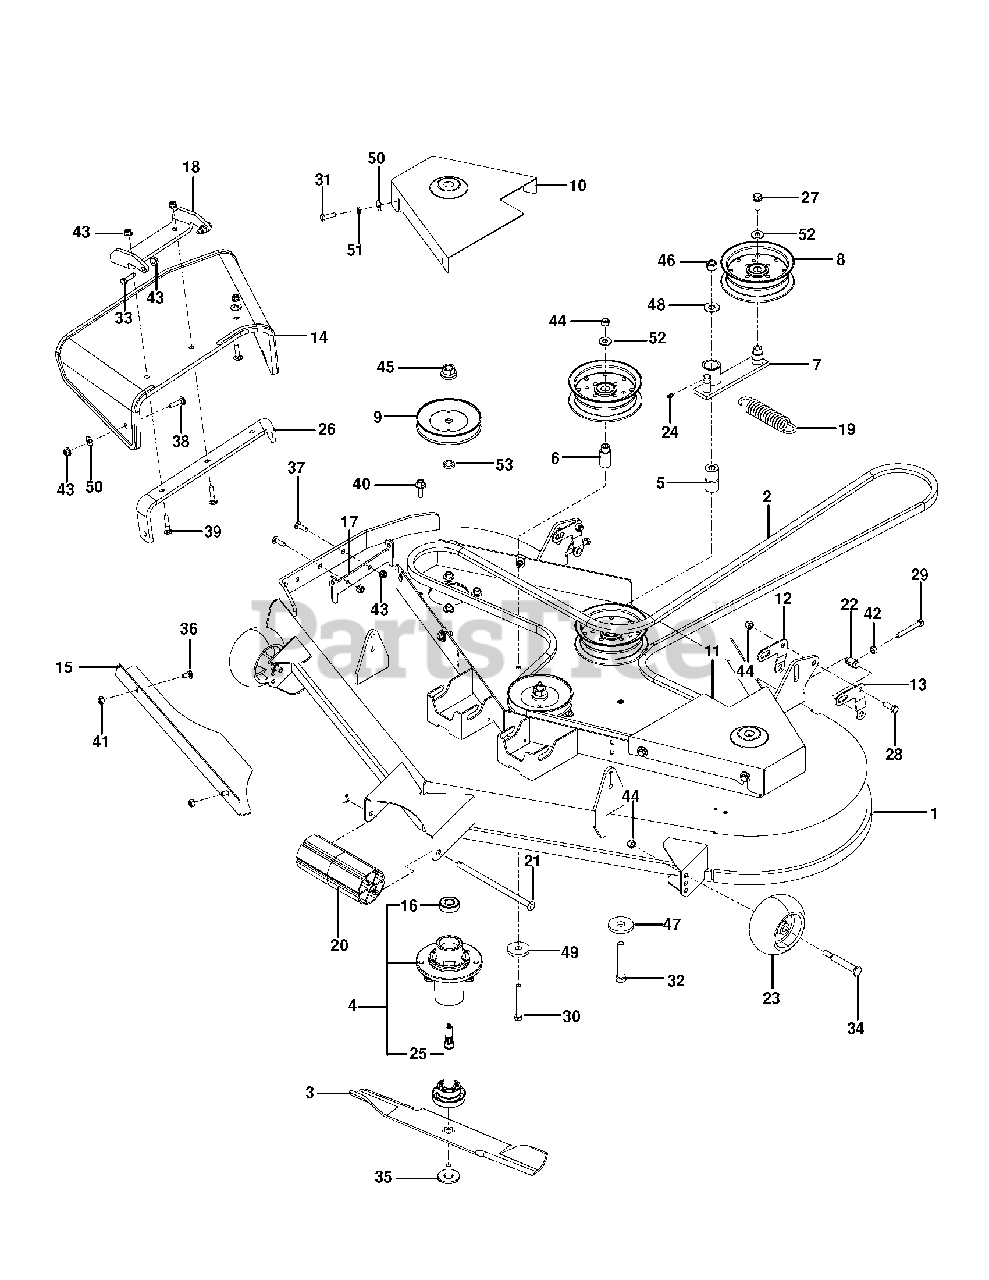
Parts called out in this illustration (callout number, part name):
1	DECK MZT 52 W/SFTY DECALS.ORNG
2	BELT, B, 148.5
3	BLADE, 18"
4	MANDREL ASM, CAST IRON
5	PIVOT BUSHING
6	IDLER BUSHING
8	PULLEY, IDLER
9	PULLEY MANDREL
10	BELT SHIELD, RIGHT 52, ORG
11	BELT SHIELD, LEFT 52, ORG
12	BRACKET.RT.PNT.MS431
13	BRACKET.LH.PNT.MS431
14	CHUTE, RUBBER DISCHARGE 52/61"
15	CONFINEMENT PLATE, 52"
17	BRACKET.M-ZT.CHUTE(BLK ONLY)RP
18	PIVOT BRACKET - CHUTE
20	NOSE ROLLER 48"
21	ROD.ROLLER.NOSE.NARROW.48"
22	TRUNION, PITCH
23	WHEEL GAGE DONUT
24	ZERK
25	SHAFT ASM MANDREL
26	BRKT, REINF - CHUTE 52/61"
27	4CS 3/8C X 1 SERRATED HEAD
29	BOLT 5/16C X 2 1/2
30	BOLT.HEX.FIN.3/8-16 X 3.GR5
31	BOLT.FIN.HEX.5/16-18UNC X 1.00
32	HCS 1/2C X 3 1/4
33	BOLT.5/16-18X1-1/4 FULL.THREAD
34	BOLT, SHOULDER
35	BOLT.WASHER.ASM.7/16-2
36	BOLT
38	BOLT, CARRIAGE 5/16X1-1/4
39	BOLT
40	SCREW, WASHER HEAD
41	NUT.71038.31-18.HEX.NYLOCK
43	5/16-18 NYLOC FLANGE NUT
44	NUT 3/8-16 NYLOC
45	NUT.FLANGE.LOCK.TOP
46	NUT.LK.W/WSH.1/2.
47	WASHER, SUPPORT
48	WASHER 1/2 FLAT
49	SPINDLE WASHER
50	WASHER
51	WASH.5/16.SLW.ZD
52	WASHER 3/8 FLAT
53	WASHER.SPACER.MANDREL
